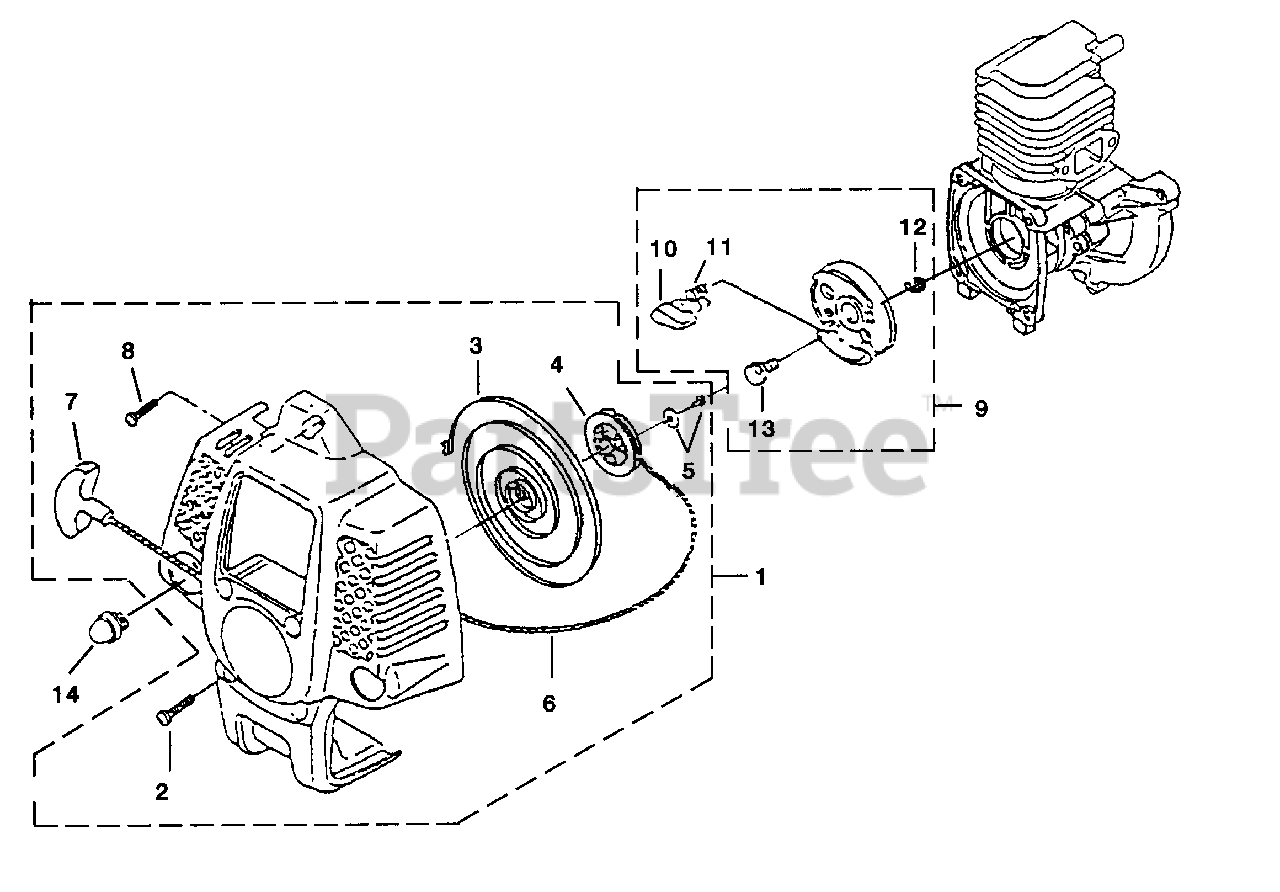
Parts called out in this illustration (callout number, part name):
1	STARTER COMPLETE
2	SCREW-Socket Hd (M5 x 18 W SW)
5	SCREW, Set
6	ROPE-Starter
8	SCREW-Tapping (M5 x 18)
9	STARTER CUP ASSEMBLY
11	SPRING-Return
13	BOLT ASSEMBLY
14	PRIMER BULB
